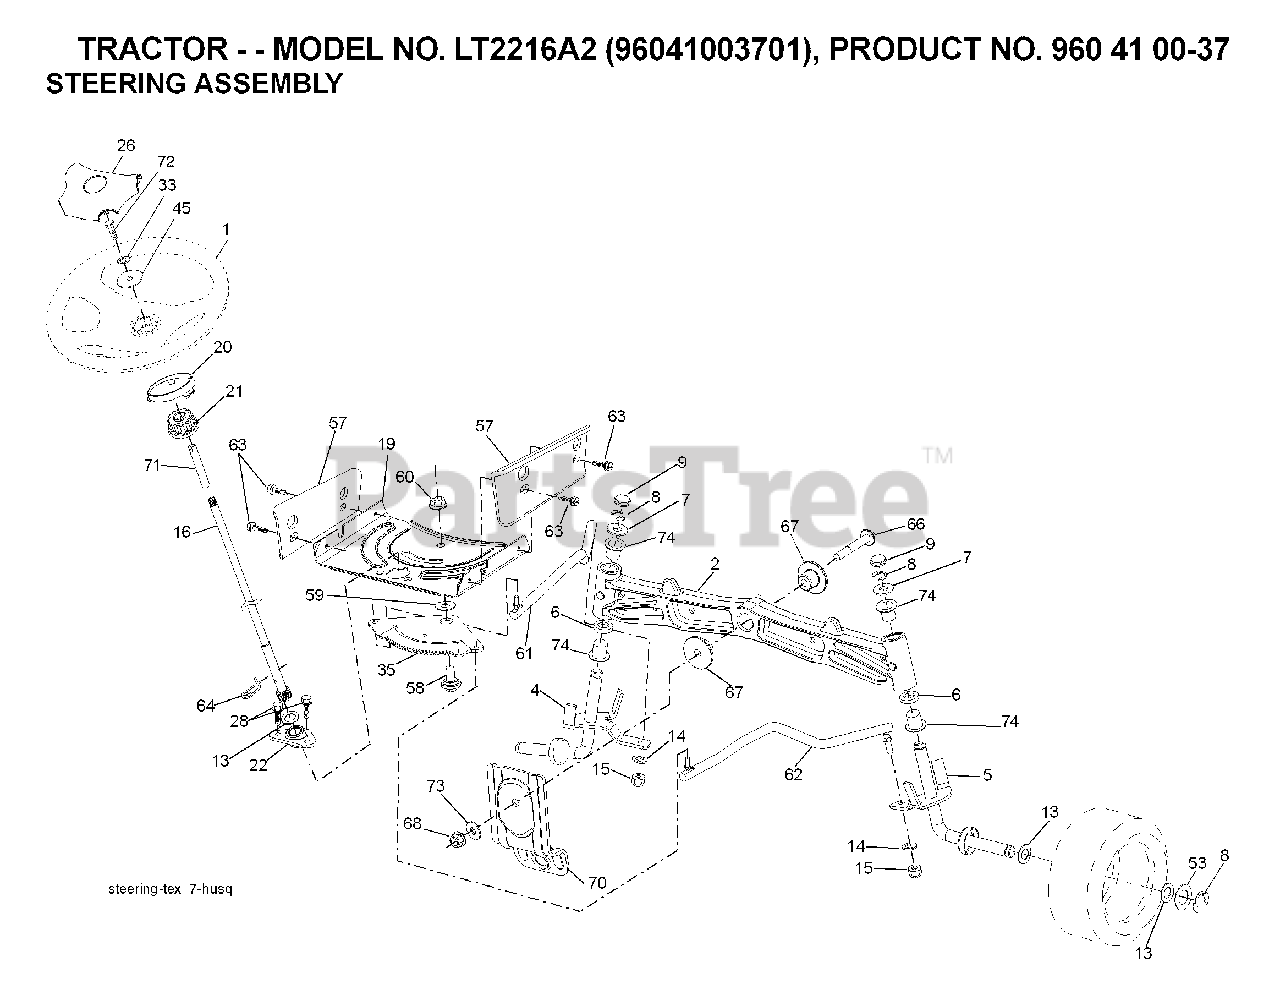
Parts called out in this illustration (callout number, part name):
1	WHEEL.STEERING.PREM.2.BLK
2	AXLE.HALF.ASM.WELDED
4	SPINDLE.WELDED.LH.15"TEX
5	SPINDLE.WELDED.RH.15"T
8	RING CLIP
9	CAP.SPINDLE
14	WASHER, LOCK 3/8
15	NUT CROWNLOCK 3/8-24
16	SHAFT STEERING
19	PLATE.STEER.DDL.NLT/NG
20	BOOT STEERING BLACK
21	ADAPTER, WHEEL STNG..
22	BUSHING.ASM.STEERING.A
26	INSERT.CAP.STRG.WH.BLACK
28	SCREW, 3/8-16X3/4
33	LOCKWASHER
35	GEAR.SECTOR.PLATE.DDL.
45	WASHER.11/32
53	WASHER.HARDENED
57	BRACKET.UPSTOP.TEX
58	BOLT.SHOULDER.SECTOR.P
59	WASHER.THURST.SECTOR.S
60	NUT FLANGE LOCK 5/8-11
61	DRAGLINK.LH.BALLSTUD.D
62	DRAGLINK.RH.BALLSTUD.D
63	SCREW
64	RETAINER.CLIP.SPRING.S
66	BOLT HEX FGHD 7/16-14 X 3 SERR
67	BUSHING.PM.FRONT AXLE
68	NUT.LOCK.FLANGE.7/16
70	BRKT.DECK.SUSPENSION.F
71	SHAFT EXTENSION STEERING
72	BOLT YT
73	WASHER.1.5X.505X.118
74	BRNG T
